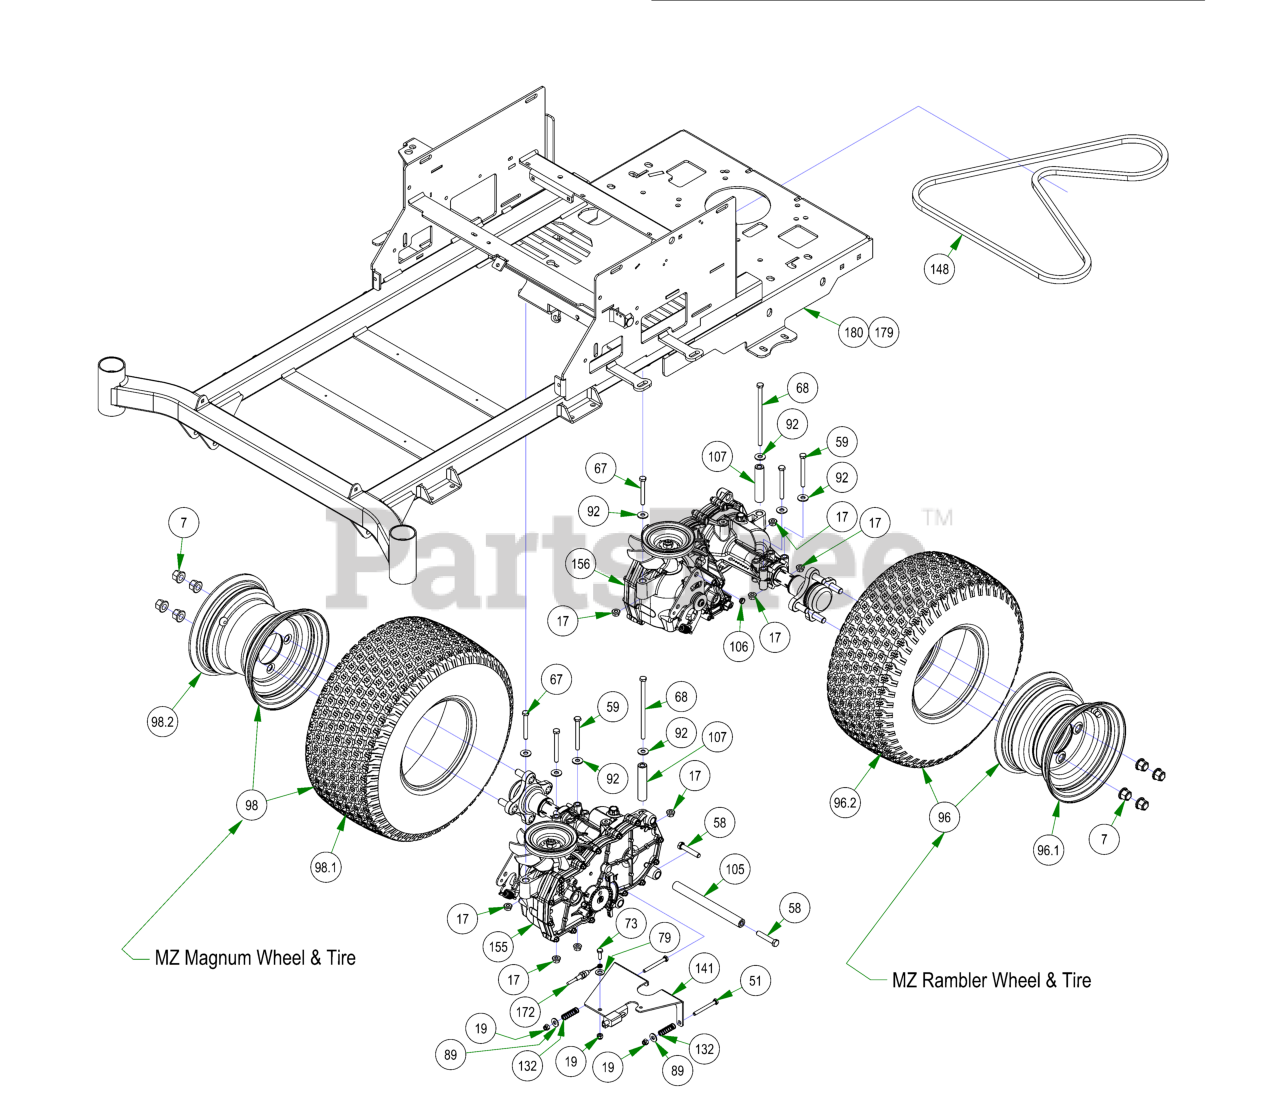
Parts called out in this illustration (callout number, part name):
7	Acorn Lug Nut
17	5/16-18 NYLON INSERT FLANGE LOCKNUT ZINC
19	1/4-20 NYLON INSERT LOCKNUT ZINC
51	1/4-20 X 2-1/2 HEX CAP SCREW (GR.2) ZINC
58	3/8-16 X 2 HEX CAP SCREW (GR.5) ZINC
59	5/16-18 X 3 HEX CAP SCREW (GR.5) ZINC
67	5/16-18 X 2-1/2 HEX CAP SCREW (GR.5) ZINC
68	5/16-18 X 6 HEX CAP SCREW (GR.5) ZINC
73	1/4-20 X 3/4 HEX CAP SCREW (GR.5) ZINC
79	.390 ID X .750 OD X .062 THK FLAT WASHER NYLON
89	1/4 USS FLAT WASHER (3/4 OD) ZINC
92	5/16 USS FLAT WASHER (7/8 OD) ZINC
96	18x8.50-8 x/*" Tire & Wheel (Black)
96.1	Rim for 022-2050-22
96.2	Tire for 022-2050-22
98	18x9.50-8 Tire and Wheel - Black Wheel
98.1	18x9.50-8 Rear Tire Only 48 MZ
98.2	Black Rear Wheel 48in MZ
105	2017 Transaxle Spacer-MZ
106	Drive Arm Transaxle Spacer
107	2017 Transaxle Spacer
132	Brake Spring
141	2017 MZ/Magnum Brake Plate Assembly
155	2017 EZT -Right -MZ Models
156	2017 EZT -Left -MZ Models
172	MZ Brake Cable
179	2022 MZ/ZT 54"-60" Frame
180	2022 MZ/ZT 42"-48" Frame
